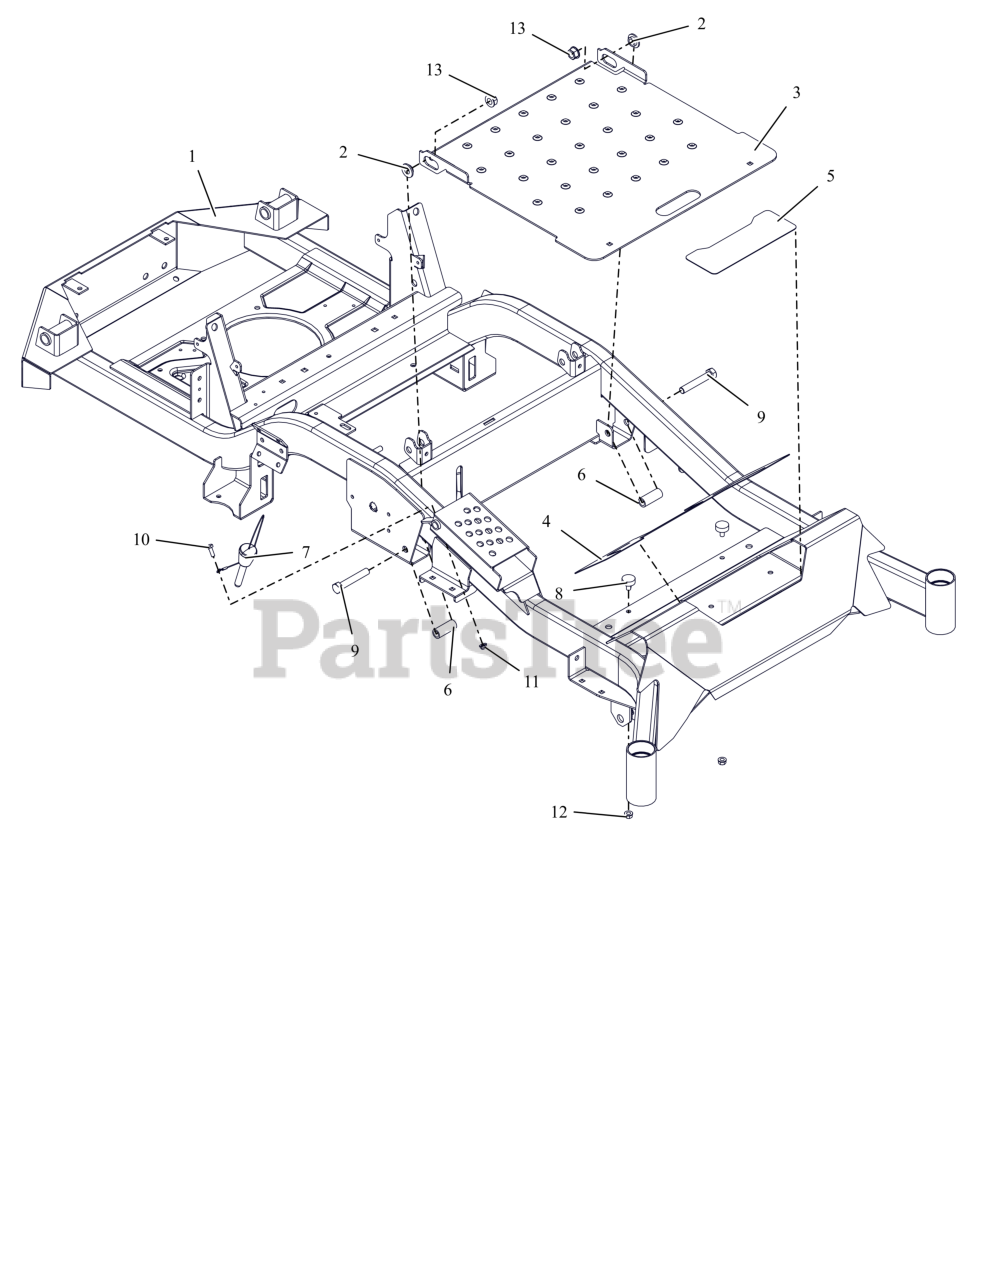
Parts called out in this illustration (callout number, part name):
1	APEX,44-52 FRAME W/SAFETY DECA
2	BSHG-FLG .515X.750X.395X1.120
3	PANEL, ACCESS
4	GRIP, FRONT
5	GRIP, STEP
6	SPACER, .515X.75X1.83
7	PIN, MAGNETIC .50X2.50
8	BUMPER, RUBBER
9	BLT, HEX .50-13X3.00 G5 ZCC
10	BLT, HEX .25-20X.75 G5 ZCC
11	NUT,NYL-FLG .25-20 GF ZCC
12	NUT,SPNLK-FLG .31-18 G5 ZCC
13	NUT-LK-TOP-FLG .500-13 GF ZCC
